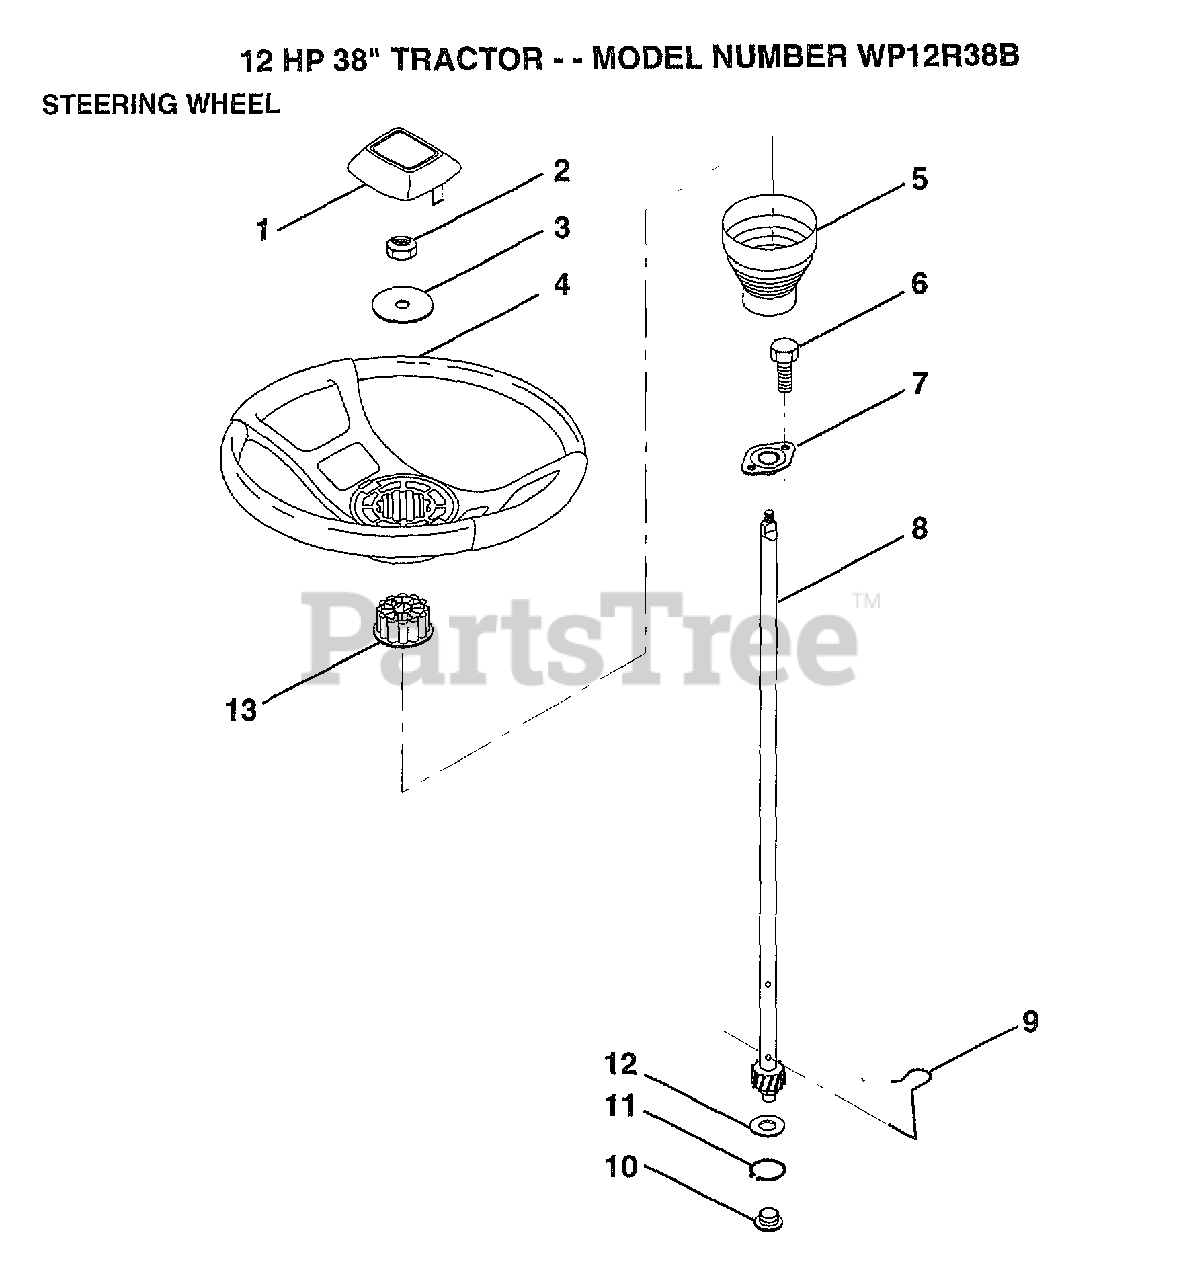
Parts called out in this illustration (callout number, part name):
1	ST WHL INSERT CAP
2	GRIPCO NUT
3	WASHER T
5	SLEEVE STEERING
9	STEERING CLIP
10	BUSHING STEER LWR
11	RING
12	WASHER LT
13	ADAPTER-WHEEL LT
